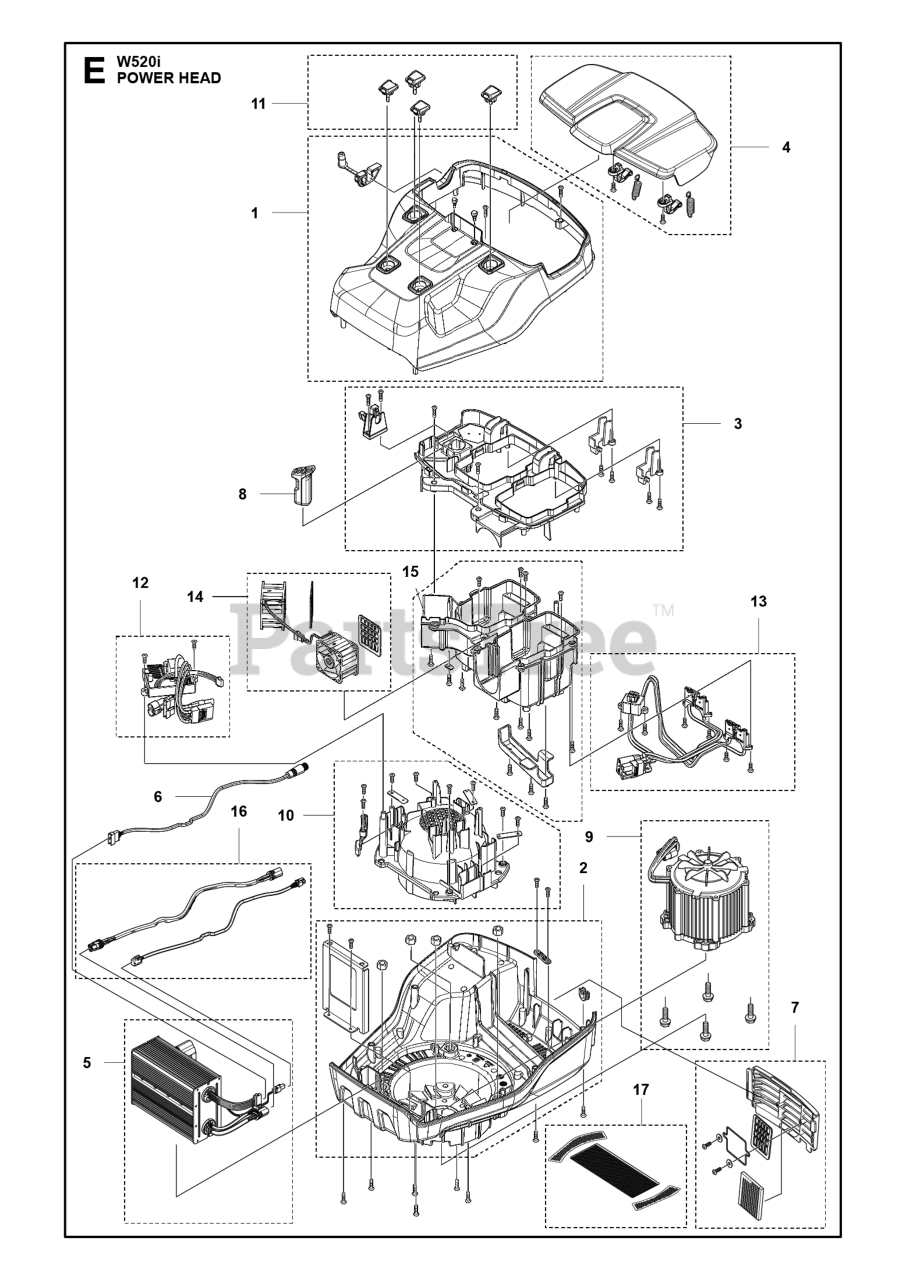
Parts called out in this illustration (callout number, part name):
3	Battery Box
13	Battery Box
14	Battery Box
15	Battery Box
